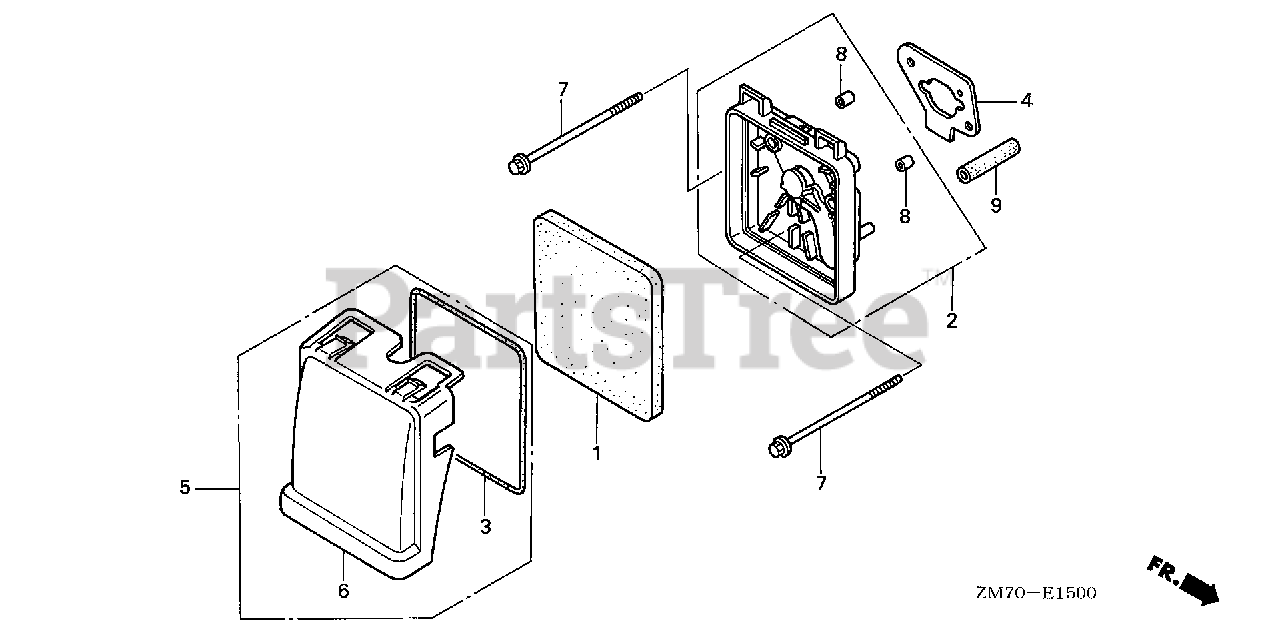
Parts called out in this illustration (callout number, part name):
1	ELEMENT, AIR CLEANER
2	HOUSING, AIR CLEANER
3	SEAL, AIR CLEANER
4	GASKET, AIR CLEANER
5	COVER, AIR CLEANER
6	COVER, AIR CLEANER
7	BOLT, FLANGE (5X80)
8	COLLAR, AIR CLEANER
9	BULK HOSE, VACUUM (7X3000) (7X75)
